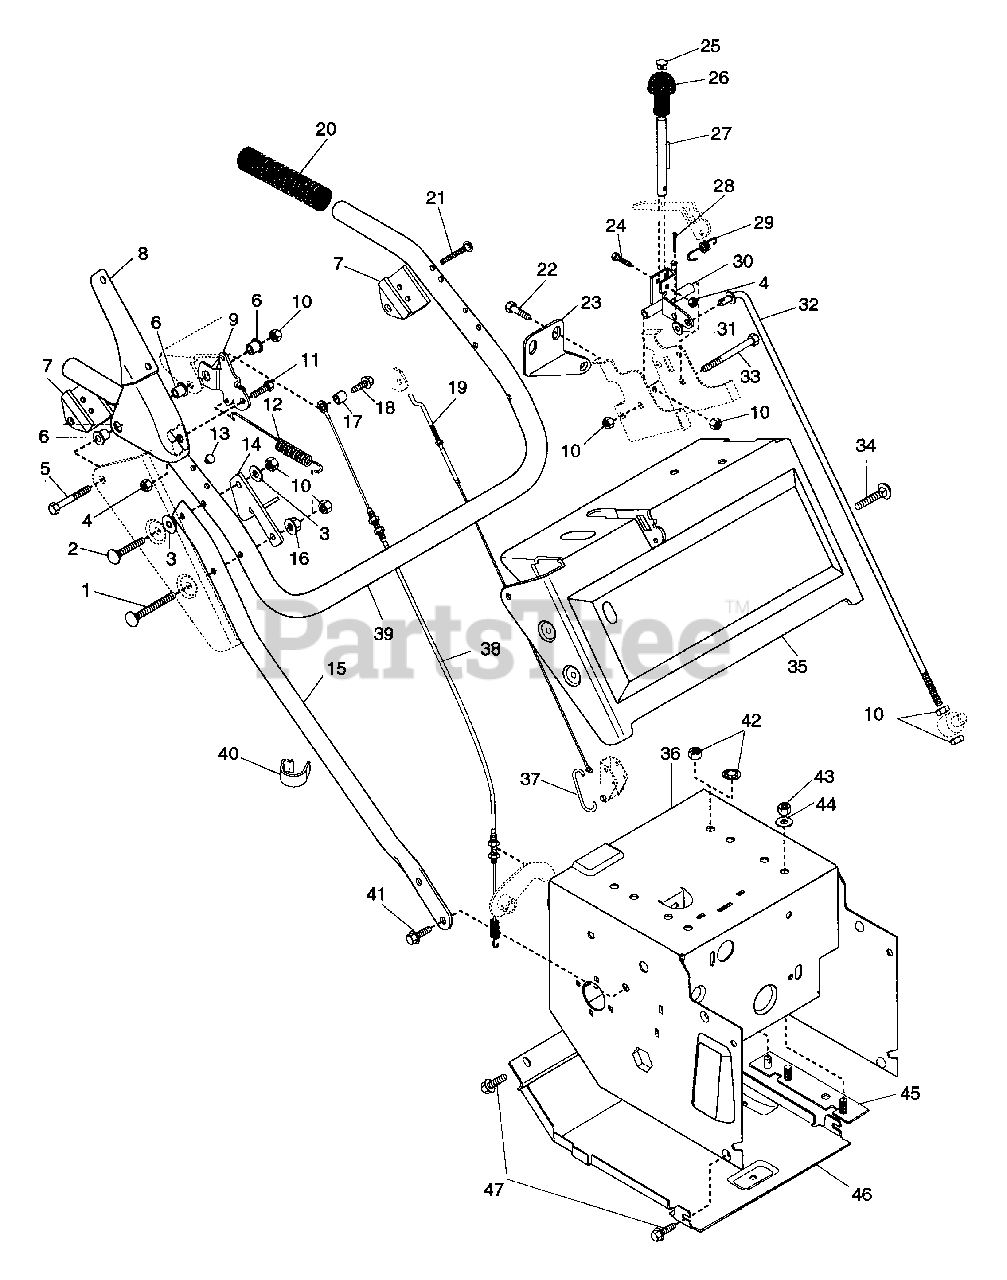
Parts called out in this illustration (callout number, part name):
1	BLT-RDHDSQNK .31-18X2.75 SHPL
2	BLT-RDHDSQNK .31-18X1.50 PL
3	WSHR-FL-STL .438X1.0X.083 PL
4	NUT-LK-CTR .250-20 PL
5	BLT-HEX .31-18X2.50 PL GR2
6	BSHG-FLG .325X.465X.333X.685
7	HANDLE PIVOT
8	CLUTCH LEVER - COATED
10	NUT-LK .312-18 GR A PL
11	BLT-HEX .25-20X.38 PL GR2
12	SG-TENS .051X.50X5.12 WLD 10.4
14	UPPER CABLE ANCHOR R H
15	L H LOWER HANDLEBAR
16	NUT-FLG. .312-18 PL
17	SPACER .230X.310X.255
18	SCR-TAP 12-24X.50 HWH PL TR
19	CABLE, ADJUSTABLE
20	HANDLE GRIP
21	SCR-TAP 12-14X1.50 CROVH PL BT
22	BLT-HEX .31-18X.50 PL GR2
23	CHUTE CRANK BRACKET
24	BLT-HEX .25-20X1.00 GR2
25	HOLE PLUG
27	ROD
28	PIN-COTR .09X.75 PL
29	SG-TENS .055X.33X1.31 WLD 7
31	WSHR-FL-STL .323X.625X.062 PL
32	SHIFT ROD
33	BLT-HEX .31-18X3.50 PL GR2
34	BLT-RDHDSQNK .31-18X1.75 SHTPL
35	PANEL W/DECAL
36	FRAME
38	CLUTCH CABLE-ATTACHMENT
39	UPPER HANDLEBAR
41	BLT-SERHFWH .31-18X.62 PL
42	NUT-LK-NYL.312-18 PL
43	NUT-HEX .312-18
44	WSHR-LK .312X.097 PL HVY
45	ENGINE MOUNT, 5L,7L,8R
46	COVER-BOTTOM
47	SCR-TAP .250-20X.37 HWH PL TR
